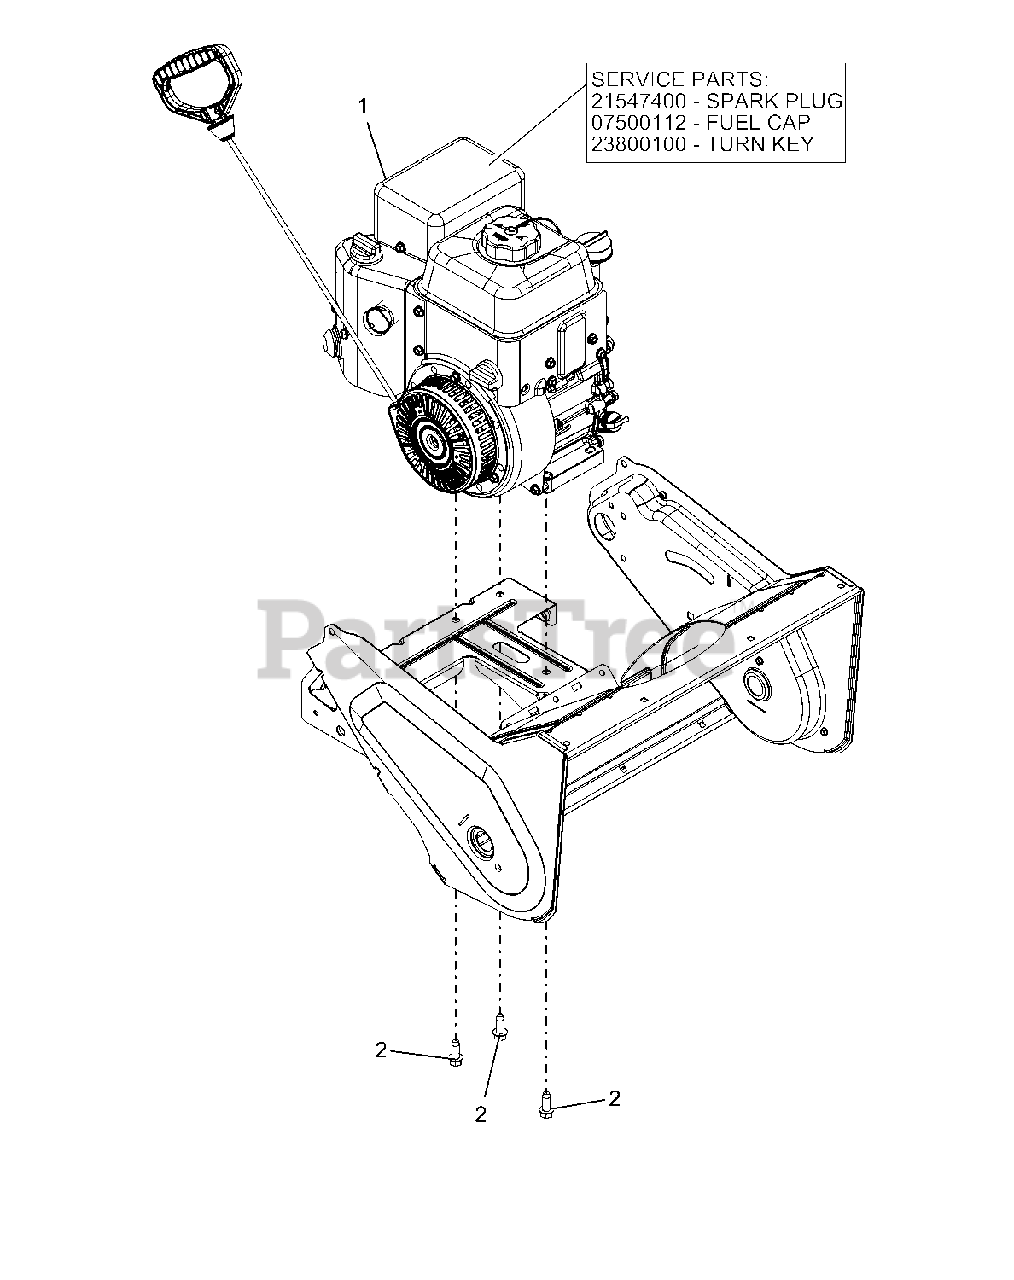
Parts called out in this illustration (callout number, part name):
1	PLUG, SPARK
1	CAP, FUEL TANK BLACK
1	KEY, TURN LCT (2/PACKAGE)
1	ENGINE, ARIENS AX136 RECOIL
2	@SCR-TAP .38-16X1.00 HWH TR YZ
